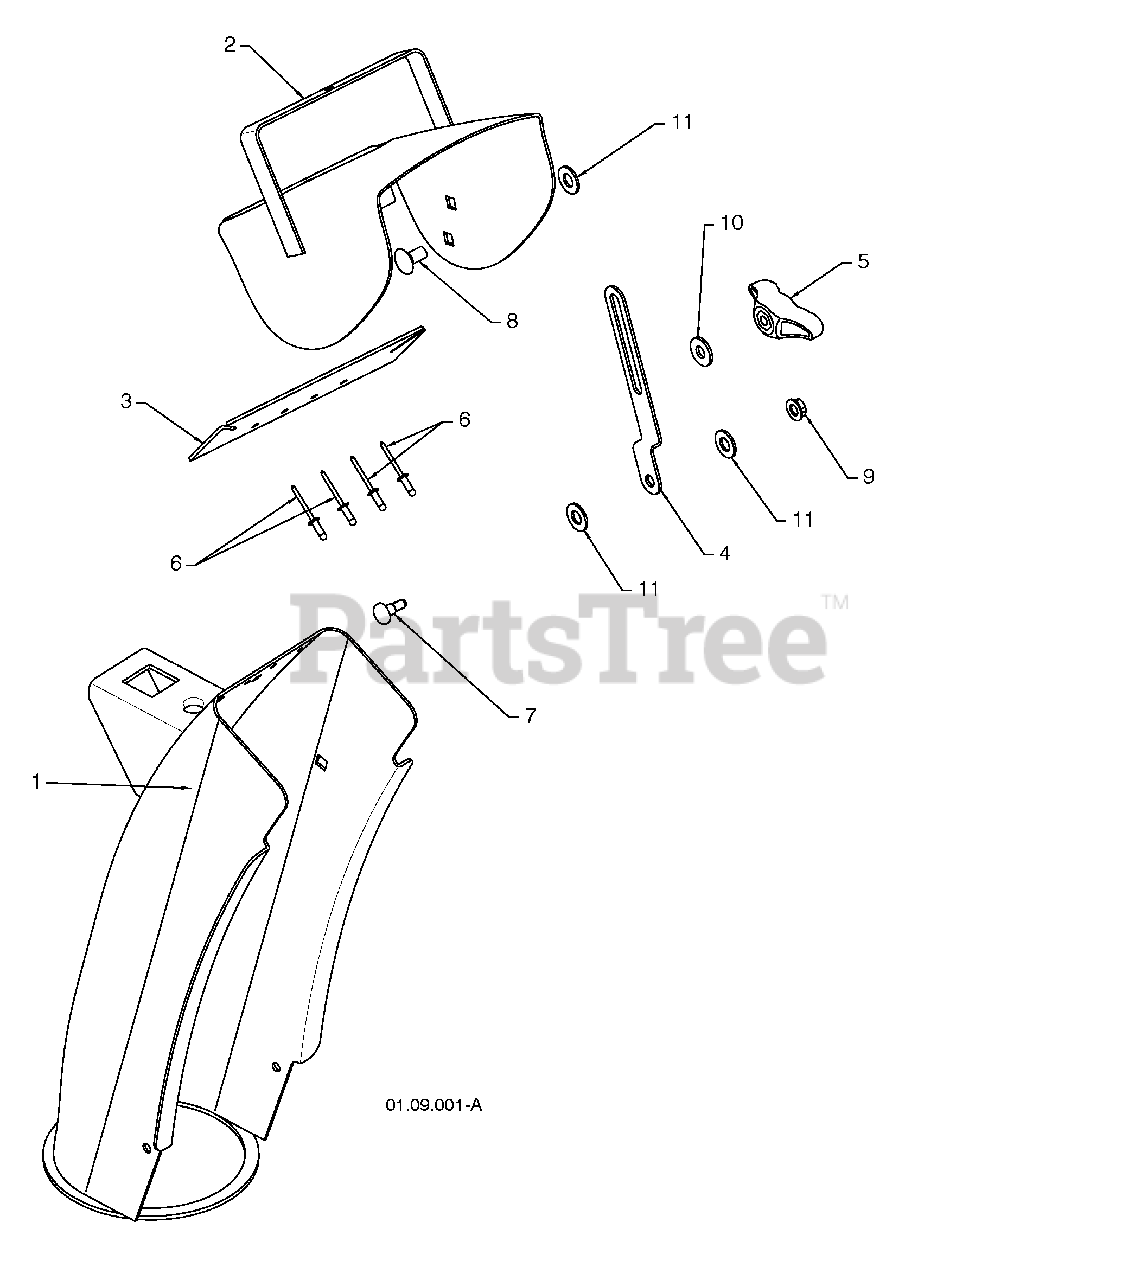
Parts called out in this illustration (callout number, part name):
1	CHUTE WELDMENT
2	DEFLECTOR WELDMENT
3	DEFLECTOR SEAL
4	STRAP
5	KNOB BLACK
6	POP RIVET
7	SHOULDER BOLT 1/4-20 X .704
8	CARRIAGE BOLT 5/16-18 X .625
9	NUT 1/4-20
10	WASHER
11	PLASTIC WASHER
